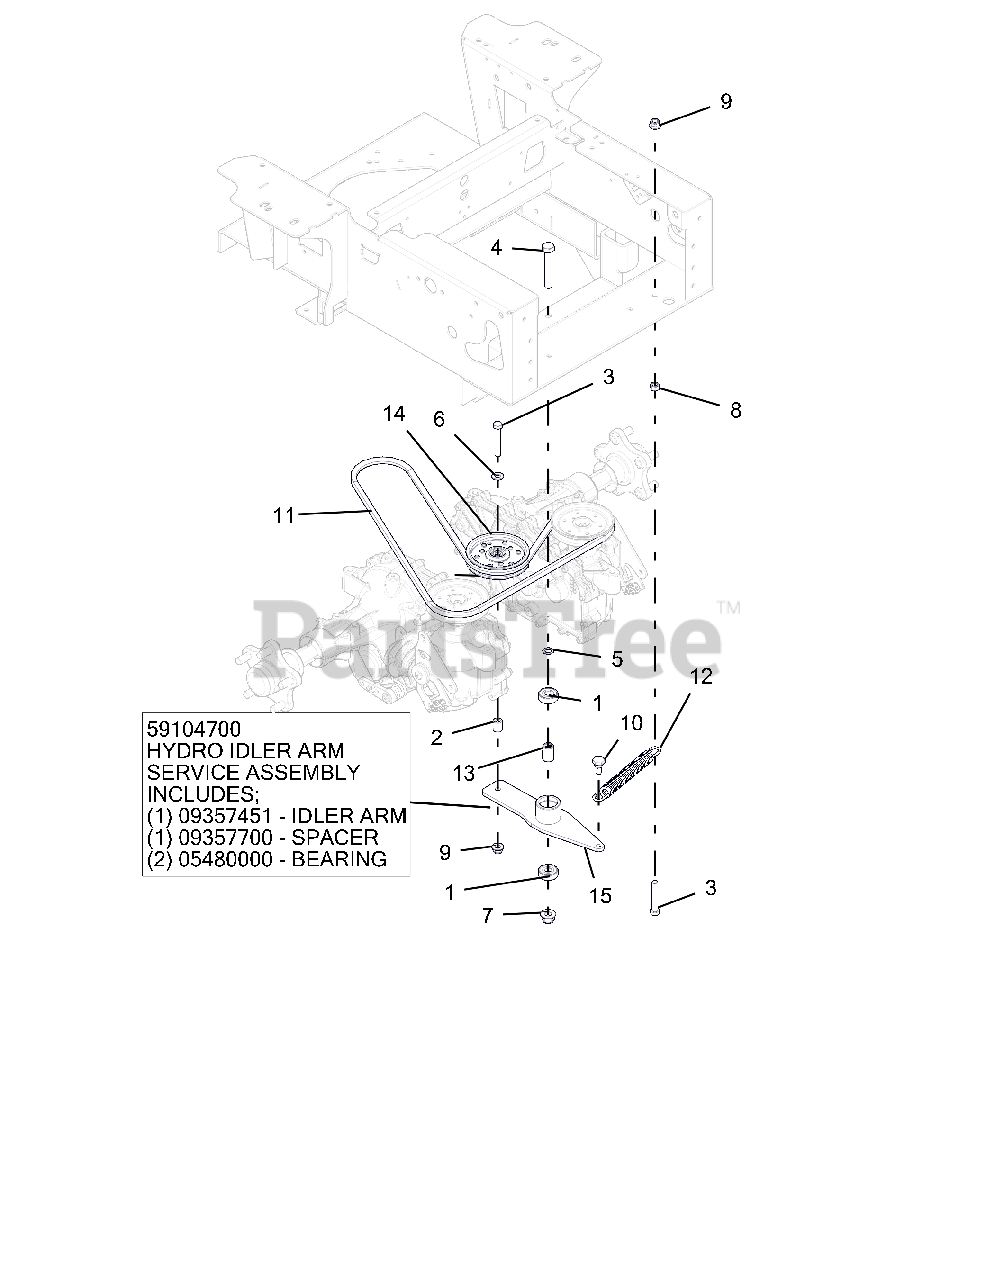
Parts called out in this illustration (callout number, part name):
1	BRG-BALL .500X1.375X.44
2	BSHG-SLV .407X.625X.750
3	BLT-HEX .38-16X2.50 GR5 YWZC
4	BLT-HEX .50-13X3.25 GR5 YWZC
5	WASHER-FLAT-STL, .500 X .750 X .020
6	WSHR-FL-STL.406X.812X.065 YWZ
7	NUT-LK-NYL-FLG .50-13 YWZC
8	NUT-HEX .38-16 YWZC
9	NUT-LK-NYL-FLG .38-16 YWZC
10	BLT, SHLDR EP .38-16X.30 HEX YZ
11	BELT, V-A-COGGED
12	SPRG, EXTENSION .120X.845X6.55 WLD
13	SPACER, .510 X .750 X 1.148
14	ASM, IDLER 4"
15	WLDMT, HYDRO DRIVE IDLER ARM-BLACK
15	HYDRO IDLER ARM SERVICE ASSEMBLY
15	IDLER ARM
